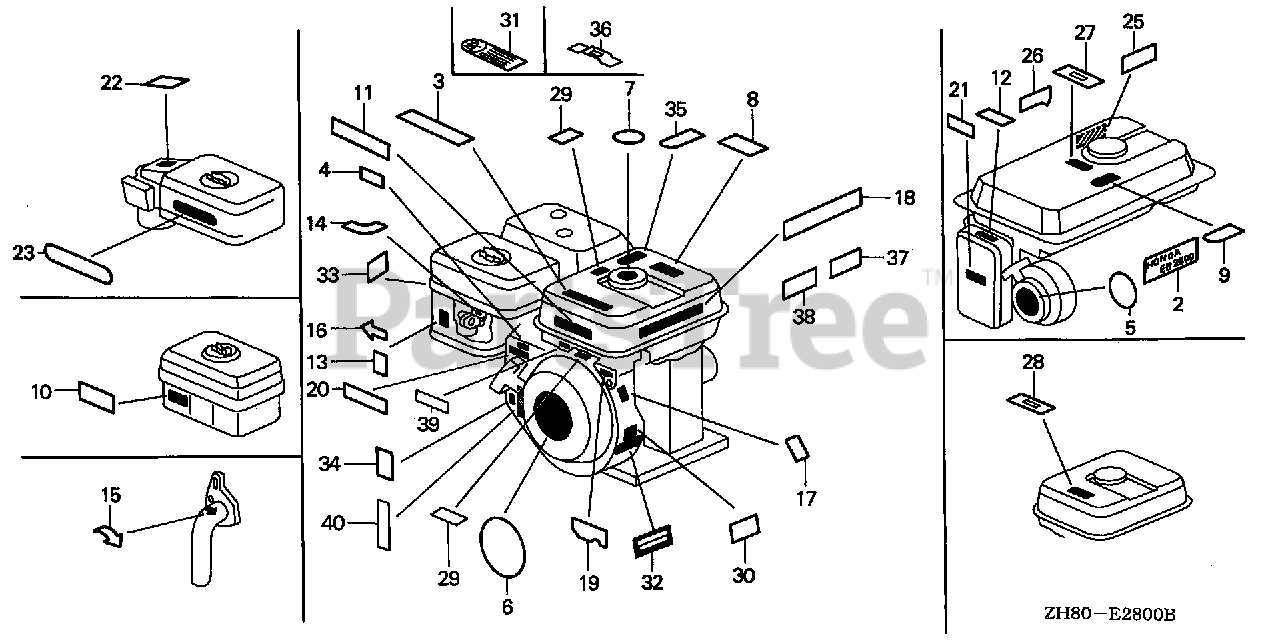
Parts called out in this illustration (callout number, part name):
6	EMBLEM (GX160 5.5)
6	EMBLEM (GX160)
7	MARK, CAUTION
11	LABEL, CAUTION (ENGLISH, ETC.)
13	MARK, CHOKE
17	LABEL, SPECIFICATION (5.5HP)
18	MARK, OIL ALERT (GERMAN)
18	MARK, OIL ALERT (FRENCH)
18	MARK, OIL ALERT (ENGLISH)
29	LABEL, FUEL CAUTION
